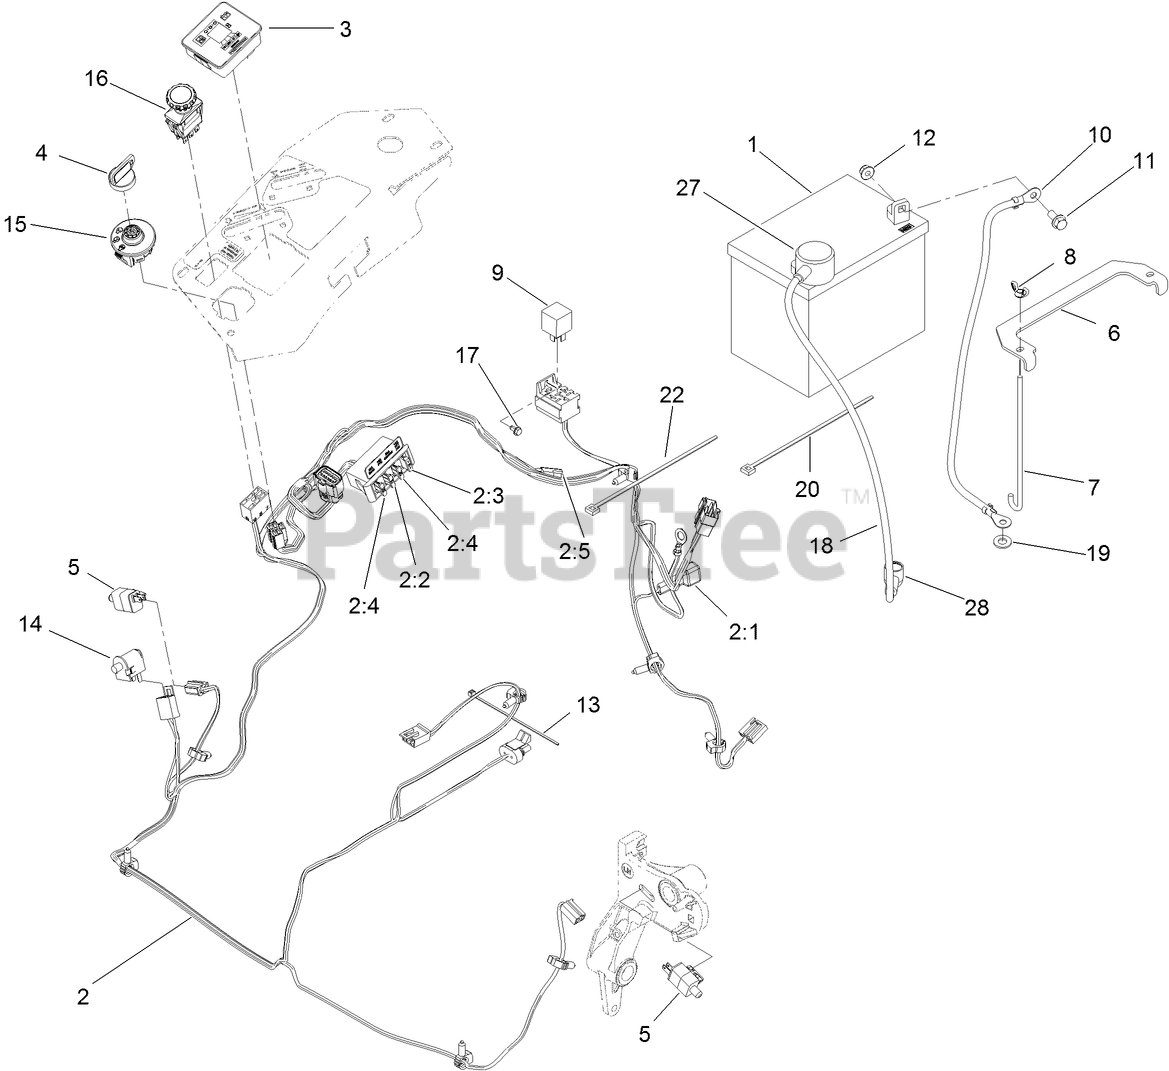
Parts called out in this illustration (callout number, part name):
1	BATTERY-DRY
2	HARNESS-WIRE, MAIN
2:2	FUSE-BLADE, 10 AMP
2:3	FUSE-BLADE, 15 AMP
2:4	FUSE-BLADE, 25 AMP
2:5	CAP-PLUG
3	FUEL/HOUR METER ASM
4	KEY-IGNITION
5	SWITCH
6	STRAP-TIE DOWN, BATTERY
7	BOLT-HOLDDOWN
8	WINGNUT
10	CABLE-BATTERY, NEGATIVE
11	SCREW-HHF
12	NUT-HF, NI
13	TIE-CABLE
14	SWITCH-BAIL
15	SWITCH-IGNITION
16	SWITCH-PTO, 10 AMP
17	SCREW-HWH
18	CABLE-BATTERY, POSITIVE
19	WASHER-FLAT
20	TIE-PLASTIC
22	TIE-PLASTIC
27	INSULATOR-BATTERY
28	INSULATOR-SOLENOID
